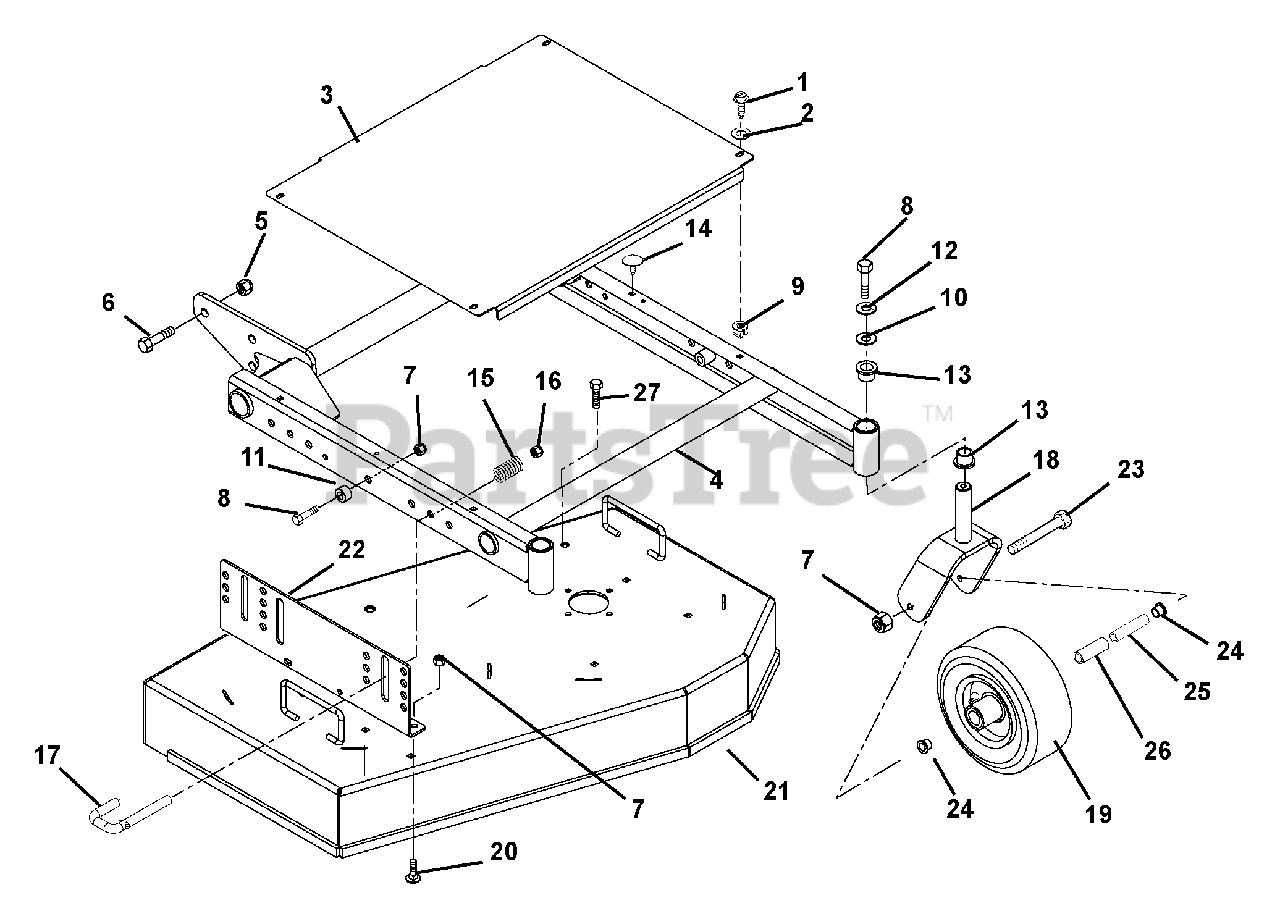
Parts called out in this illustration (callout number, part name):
1	@SCR-TAP .25-20X.50 HWH TR YWZ
2	@WSHR-FL-STL.281X.62X.065 YWZC
3	COVER - BELT - PRO - 32"
4	WMT - MOWER FRAME - 32"
5	@NUT-LK-NYL .625-11 YWZC
6	@BLT-HEX .62-11X1.50 GR5 YWZC
7	@NUT-LK-TOP-FLG .38-16 YWZC
8	@BLT-HEX .38-16X1.25 GR5 YWZC
9	GRMT,PLASTIC
10	WSHR-FL-STL .380X1.50X.125YWZC
11	BSHG-SLV .391X.688X.52 PM
12	@WSHR-LK .38X.094 REG YWZC
13	BSHG-FLG 1.00X1.25X1.50X1.50EP
14	BUMPER GROMMET
15	SPRG, COMP .058X.65X2.13 WLD15
16	@NUT-LK-CTR .50-13 YWZC
17	PIN - LATCH
18	WMT - CASTER FORK
19	WHEEL 9 X 3.50 SEMI-PNEUMATIC
20	@BLT-RDHDSQNK .38-16X1.00 G5YZ
21	KIT-32" REAR DIS DECK W/DECALS
22	KIT-MOWER SIDE SUPT BRKT-RH&LH
23	BLT-HEX .38-16X5.50 YWZC
24	RTNR-BEARING-PRO
25	BEARING .625 X .380 X 4.08
26	BEARING, ROLLER--PRO
27	@BLT-HEX .38-16X1.00 GR5 YWZC
